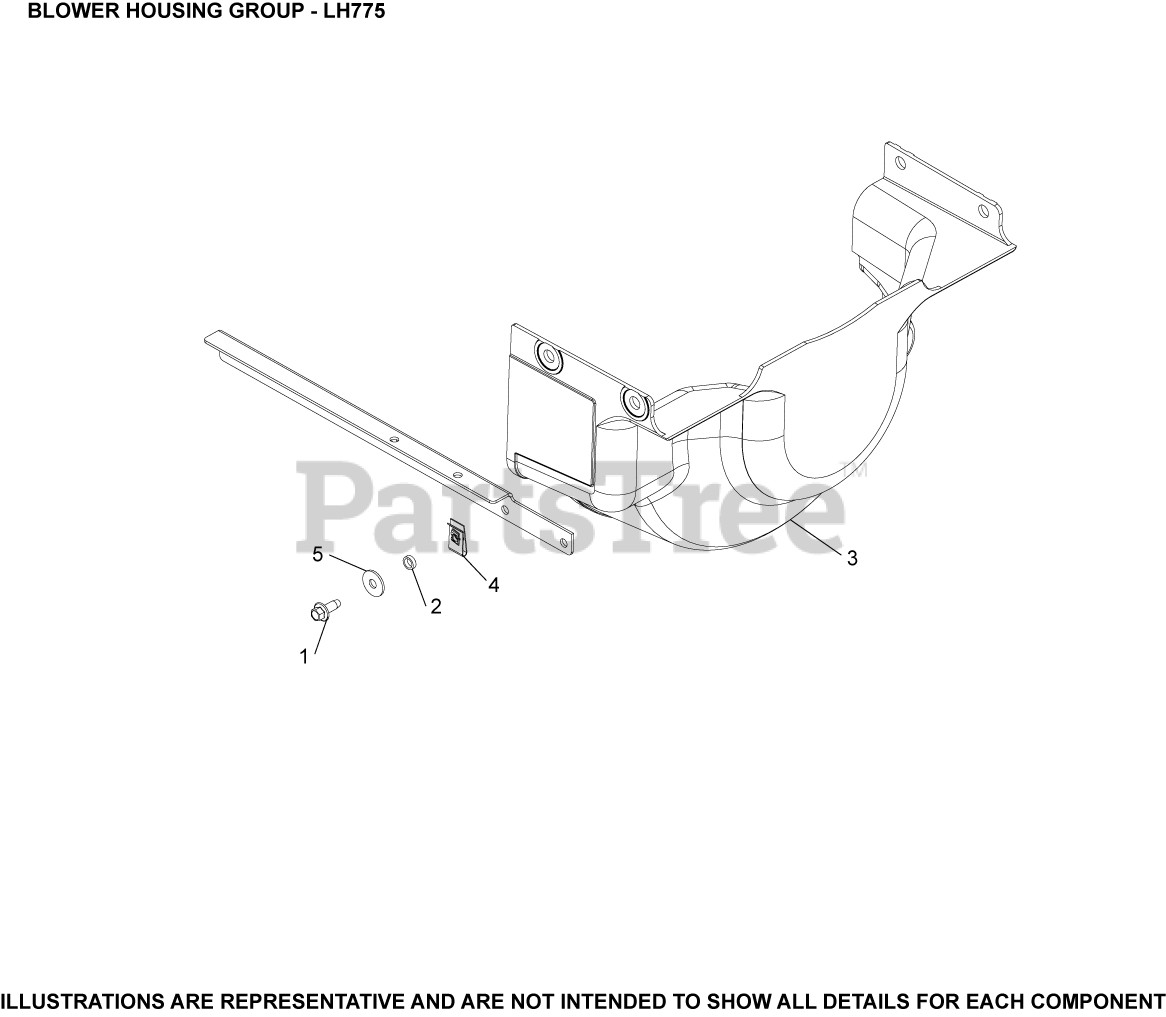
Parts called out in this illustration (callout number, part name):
1	SCREW, THREAD FORMING
3	COVER, ENGINE FLYWHEEL
5	WASHER, FLAT 1/4"
